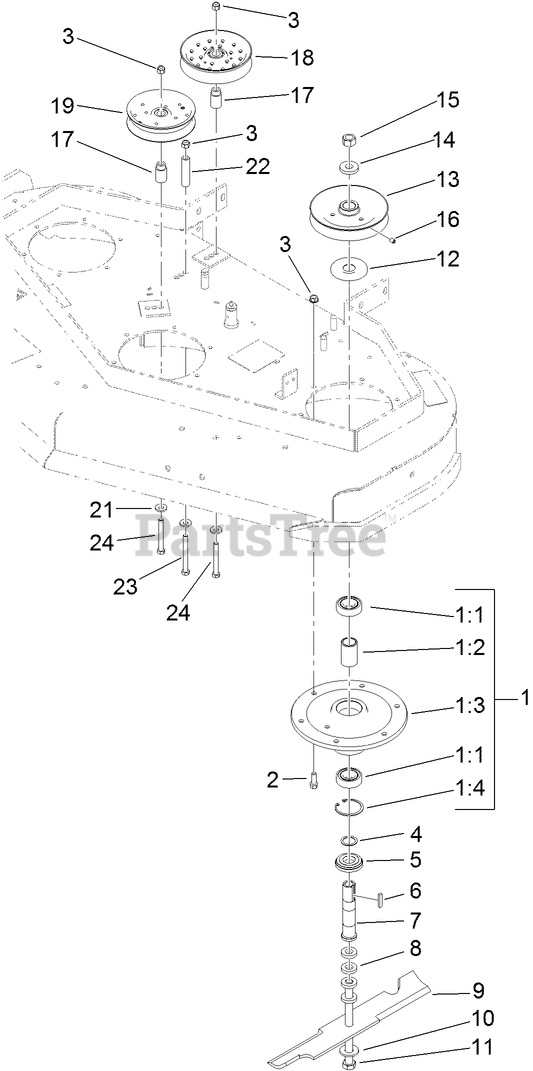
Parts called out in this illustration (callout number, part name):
1	SPINDLE HOUSING ASM
1:1	BEARING-BALL, 1 INCH
1:2	SPACER-BEARING
1:3	HOUSING-SPINDLE
1:4	RING-SNAP
2	SCREW-HWH
3	NUT-HF, NI
4	WASHER-SPACER
5	SPACER-GUARD, BOTTOM
7	TUBE-SPINDLE, SHORT
8	SPACER
9	BLADE-16.5 INCH (HIGH FLOW)
10	WASHER-SPRING
11	SCREW-CAP, HH
12	Guard-Bearing, Top
13	SHEAVE
14	WASHER-RETAINER, SHEAVE
15	NUT-HEX
16	SETSCREW
17	BUSHING-IDLER
18	PULLEY-IDLER, FLAT
19	PULLEY-IDLER
21	WASHER-BELLEVILLE
22	SPACER
23	SCREW-HH
24	SCREW-HH
